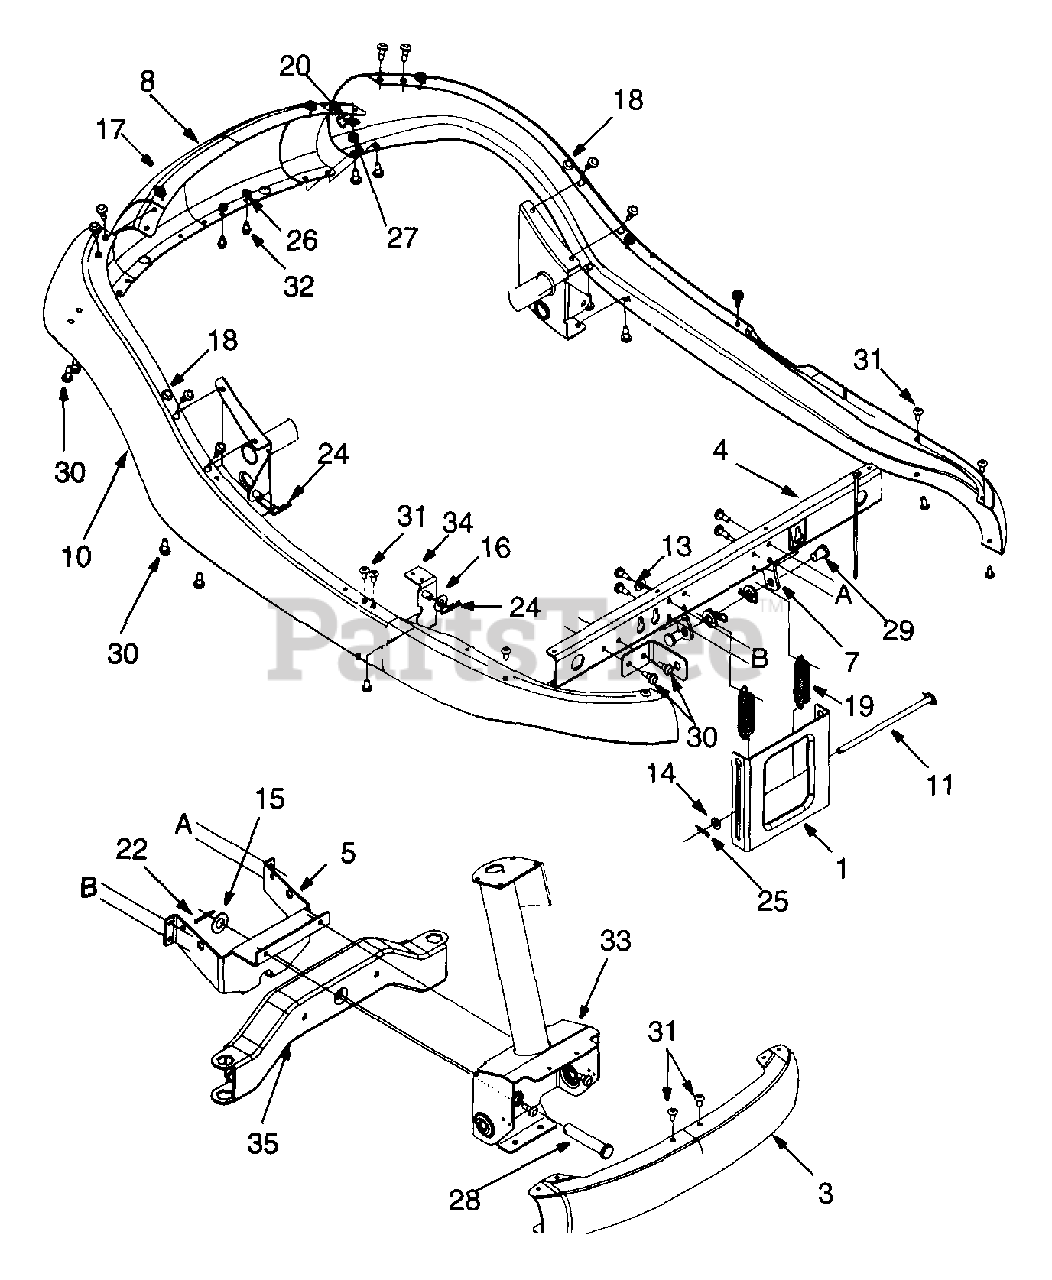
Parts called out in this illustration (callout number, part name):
13	Flat Washer .344 X .750 X .120
14	Flat Washer 5/16
15	Flat Washer.64 I.D. X 1.24 X .06
16	Flat Washer 3/8 X 1.00 X .030
17	Bumper
18	Rubber Bumper
19	Extension Spring
20	Clamp
22	Cotter Pin
24	Cotter Pin
25	Cotter Pin
26	Hex nut
27	Hex Nut 1/4-20
28	Clevis Pin
29	Lift Bracket Pin
30	TL Screw 5/16-18 x .75
31	Torx Mach. TT scr.
32	Hex TT Screw 1/4-20
